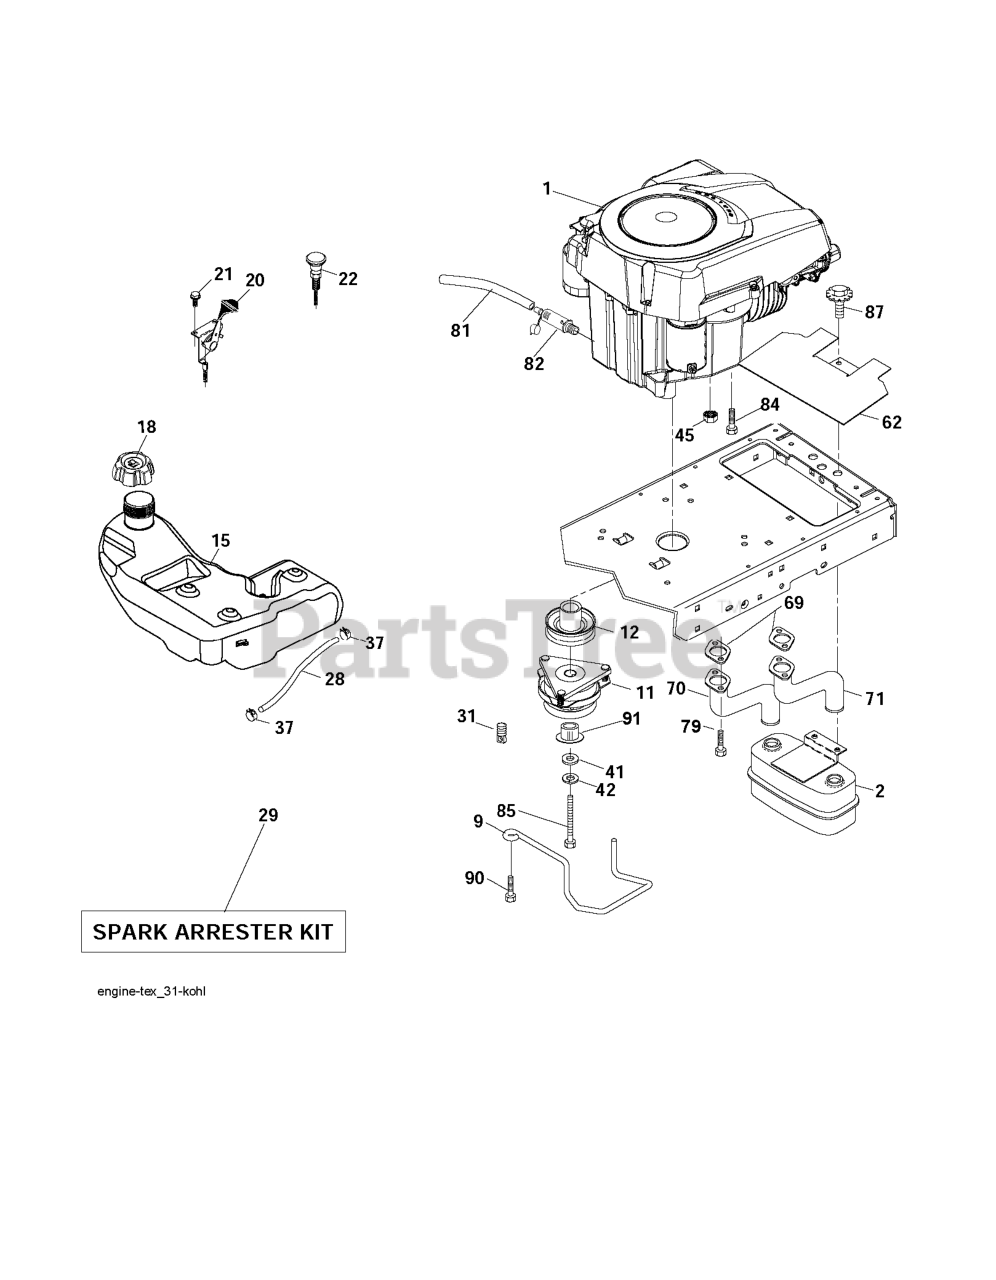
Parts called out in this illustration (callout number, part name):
2	MUFFLER.TWIN.CYL.LOW.TONE
9	KEEPER.BELT.ENGINE.4.2
11	CLUTCH MZ ZTR GT.48/54"1.125"
12	PULLEY ENGINE
15	TANK.FUEL.4GAL
18	CAP.FUEL.TANK.3"GREY
20	THROTTLE CONTROL
21	SCREW
22	CONTROL.CHOKE.ERGO.PUSH-IN.BLA
28	FUEL LINE 54"
29	KIT.SPARK ARRESTOR 794945 B&S
37	HOSE CLAMP
42	LOCKWASHER
45	NUT
62	RP SHIELD HEAT MUFFLER
69	GASKET.EXHAUST.KOHL.CV18-CV26
70	RP.PIPE-EXHAUST LH
71	RP.PIPE-EXHAUST RH
79	SCREW.SOCKET HD.5/16-1
81	TUBE, DRAIN OIL ASM.
82	PLUG DRAIN OIL EASY
84	SCREW 3/8-16X1
85	BOLT HEX 7/16-20 X 3.75 GR. 5
87	BOLT.5/16-18UNCX1.W/SEMS.BLK
90	SCREW 3/8-16X1
91	BUSHING.1.375OD
